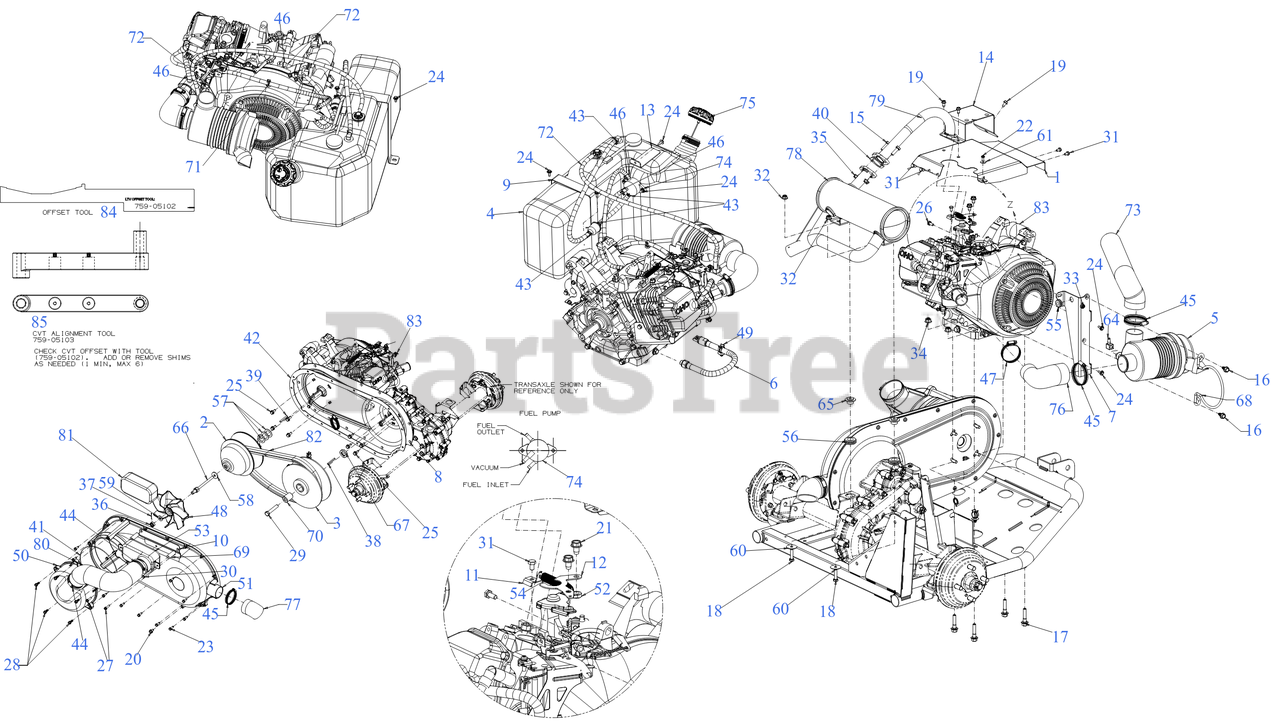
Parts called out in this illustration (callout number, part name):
1	ENGINE COVER ASSEMBLY
2	CVT DRIVER CLUTCH ASSEMBLY
3	CVT DRIVEN CLUTCH ASSEMBLY
4	FUEL TANK ASSEMBLY (5 GALLON)
5	AIR CLEANER FILTER ASSEMBLY
6	OIL DRAIN HOSE ASSEMBLY (M14-1.5MM)
8	BACK COVER PLATE
9	FUEL TANK STRAP BRACKET
10	CVT INTAKE TUBE SUPPORT
11	SPRING RETENSION BRACKET
12	THROTTLE MOUNTING BRACKET
13	FUEL TANK TOP BRACKET
14	AIR INLET COVER
15	SCREW 5/16-18 x 1.0 GR5
16	SCREW 5/16-18 x .750
17	SCREW 3/8-18 x 1.75 GR5
18	SCREW 5/16-18 x 1.25 GR5
19	SCREW 1/4-20 X.500
20	SCREW 5/16-18 x .625
21	SCREW 5/16-18 x .500
22	SCREW M5-.8X10MM SLOT/TORX
23	SCREW-TT 1/4-20 x .875
24	SCREW M6-1 x .625
25	HEX FLANGE BOLT 5/16-24:0.75
26	SCREW 1/4-20 x .620 GR5
27	SCREW 1/4-20 x 1.00
28	SCREW 1/4-15 x .750
29	SCREW 1/2-20 x 2.75 GR8
30	SCREW 1/4-20 x 2.375
31	SCREW M6-1.0X10MM GR8.8
32	FLANGE LOCK NUT 5/16-18
33	FLANGE LOCK NUT
35	FLANGE NUT
36	HEX NUT CASTLE
37	COTTER PIN-3/32 DIA x 1.00
38	SQUARE KEY 3/16 x 3/16 x 2
39	KEY 1/4 x 3/16
40	EXHAUST GASKET
41	O-RING 7.98 x 8.137 x 0.103
42	CVT COVER SEAL
43	HOSE CLAMP 1/20
44	HOSE CLAMP
45	HOSE CLAMP 2-3"
46	HOSE CLAMP 0.470
47	ADJUSTABLE HOSE CLAMP 1.31-2.25"
49	DRAIN HOSE CLIP
50	CVT FAN COVER
51	CVT COVER
52	CONTROL PANEL COVER
53	CVT FILTER HOUSING
54	EXTENSION SPRING
56	GROMMET .75 x 1.063 x .4375
57	FLAT WASHER
58	FLAT WASHER
59	FLAT WASHER .510X.995
60	FLAT WASHER .322 ID x 1.25 x .060
64	90 DEGREE FITTING
65	SHOULDER SPACER .750 x .145
66	THREADED FAN ROD
67	SHOULDER SPACER
68	AIR FILTER STRAP ROD
70	CVT DRIVEN SPACER
71	FUEL HOSE LOW PERMEATION 28"
72	FUEL HOSE LO PERMEATION 62"
73	AIR INLET HOSE
74	ENGINE FUEL PUMP
76	FUEL CAP W/TETHER VENTED
77	CVT EXHAUST HOSE
79	EXHAUST PIPE
80	CVT INTAKE TUBE
81	CVT INLET FILTER
82	CVT BELT 4X2
83	COMPLETE ENGINE LTV
84	TOOL - CVT OFFSET
85	TOOL - CVT ALIGNMENT
